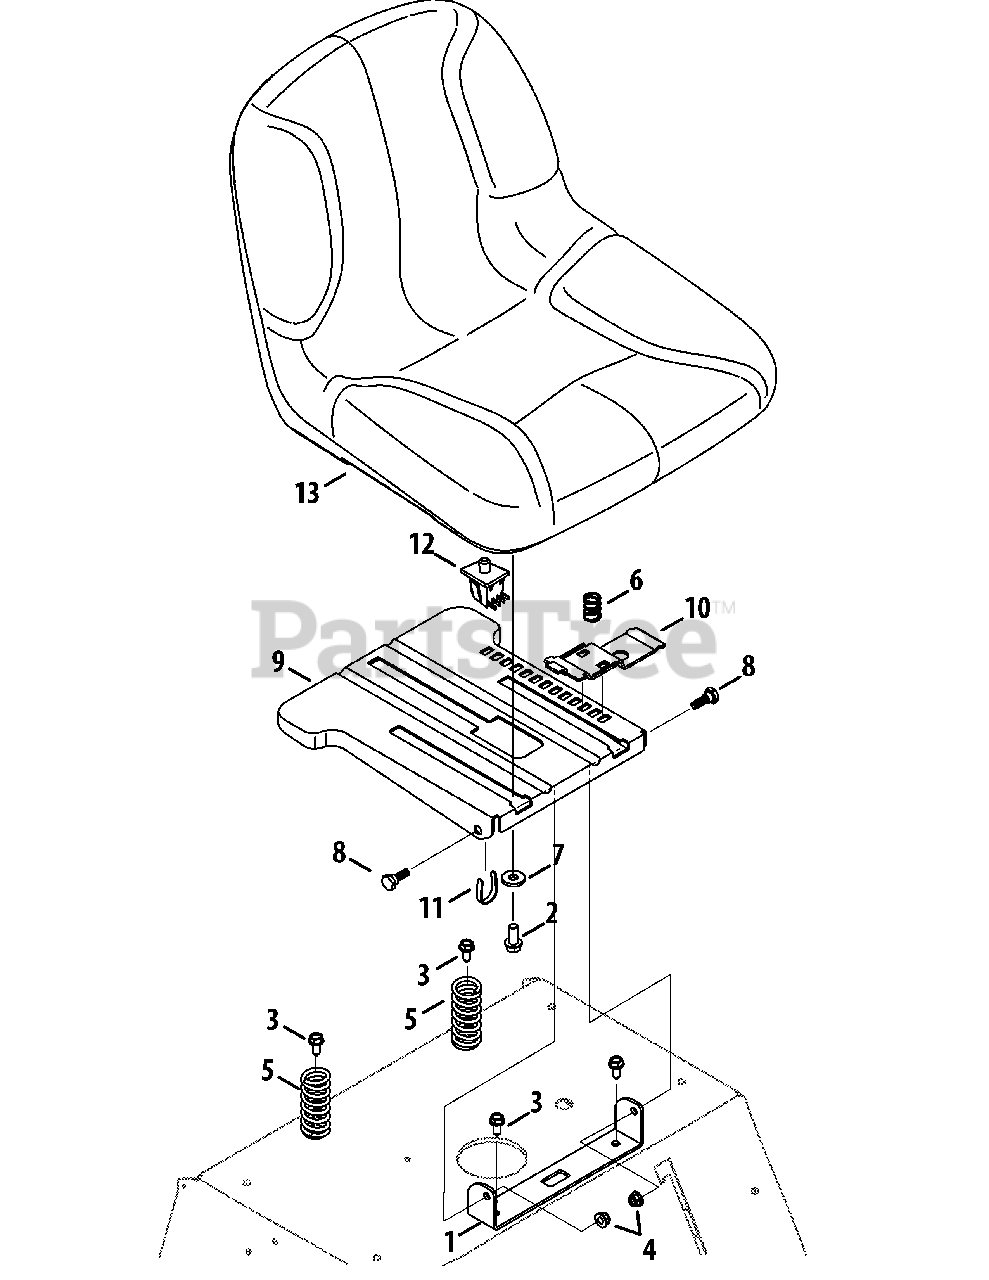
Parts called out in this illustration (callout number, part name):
1	Seat Bracket
2	Hex Flange Bolt, 3/8-16 x .875
3	Hex Washer Screw,5/16-18 x .750
4	Flange Lock Nut,5/16-18
5	Compression Spring, 1.50 x 3.90 x .200
6	Compression Spring, .68 x 1.065 x .055
7	Flat Washer, .385 x 1.0 x .135
8	Shoulder Screw, .437 x .268 x5/16-18
9	Seat Mount Bracket
10	Seat Adjustment Lever
12	Seat Switch
13	High Back Seat
